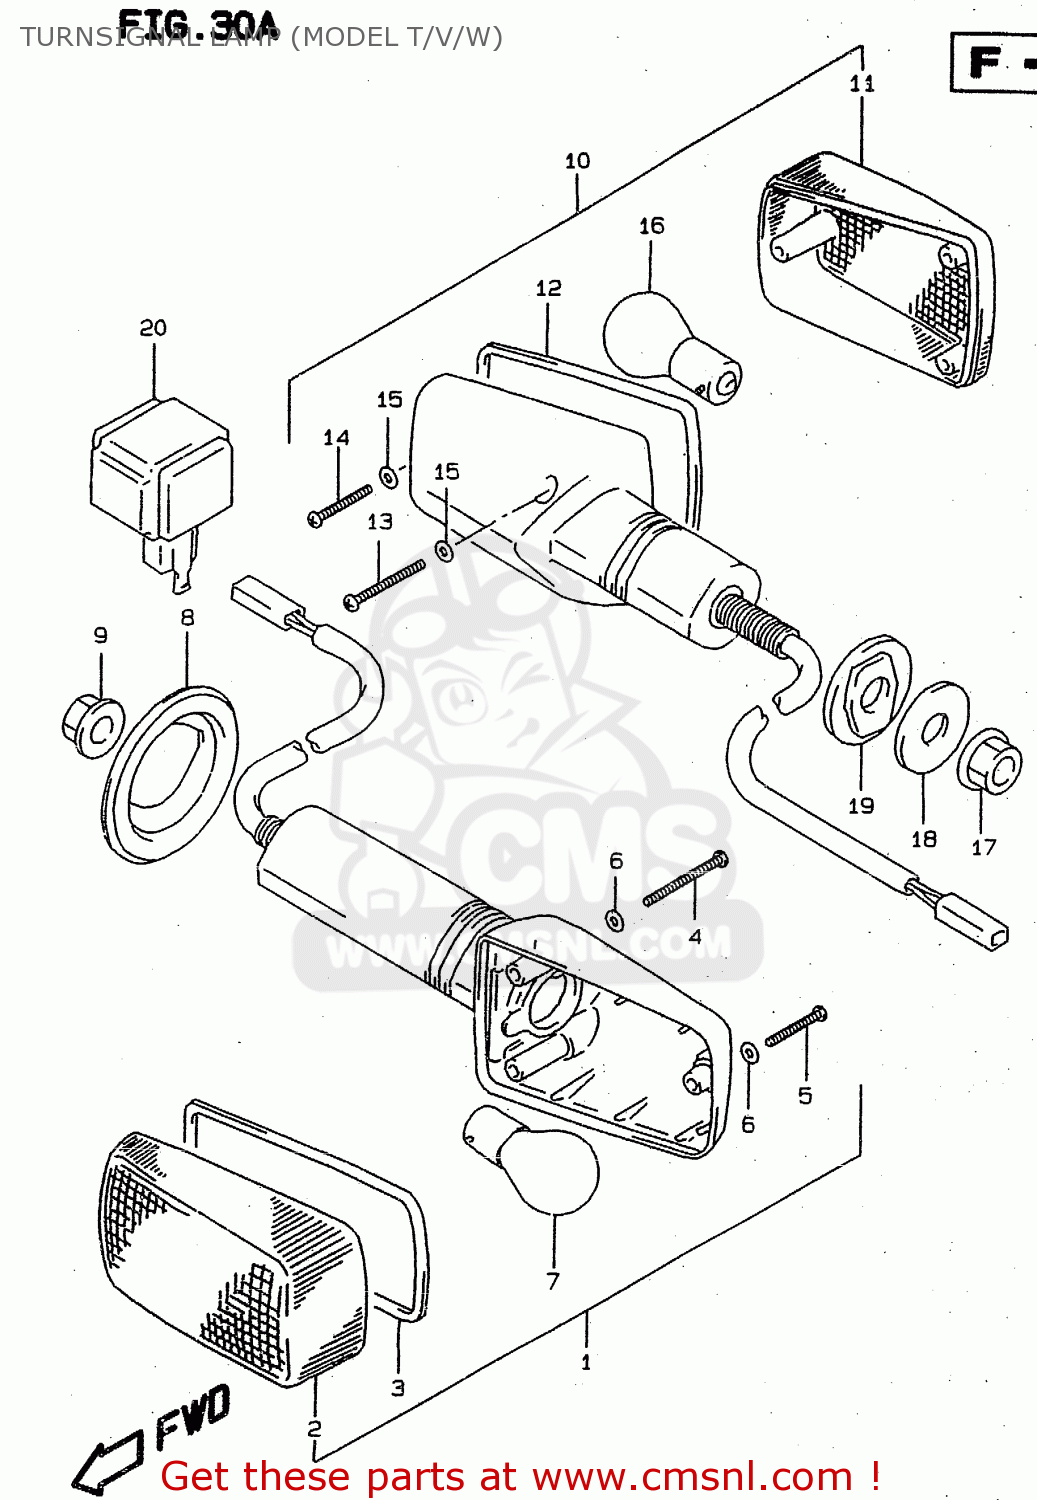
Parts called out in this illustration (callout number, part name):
1	LAMP ASSY,FR TURN SIGNAL
2	LENS
3	GASKET (NAS)
4	SCREW(3X30)
5	SCREW
6	GASKET (NAS)
7	BULB(12V21W)
8	GROMMET
9	NUT
10	LAMP ASSY,RR TURNSIGNAL
11	LENS
12	GASKET (NAS)
13	SCREW(3X30)
14	SCREW
15	GASKET (NAS)
16	BULB(12V21W)
17	NUT
18	WASHER(10.5X30X2.3)
19	SPACER,RR TURNSIGNAL
20	RELAY ASSY
